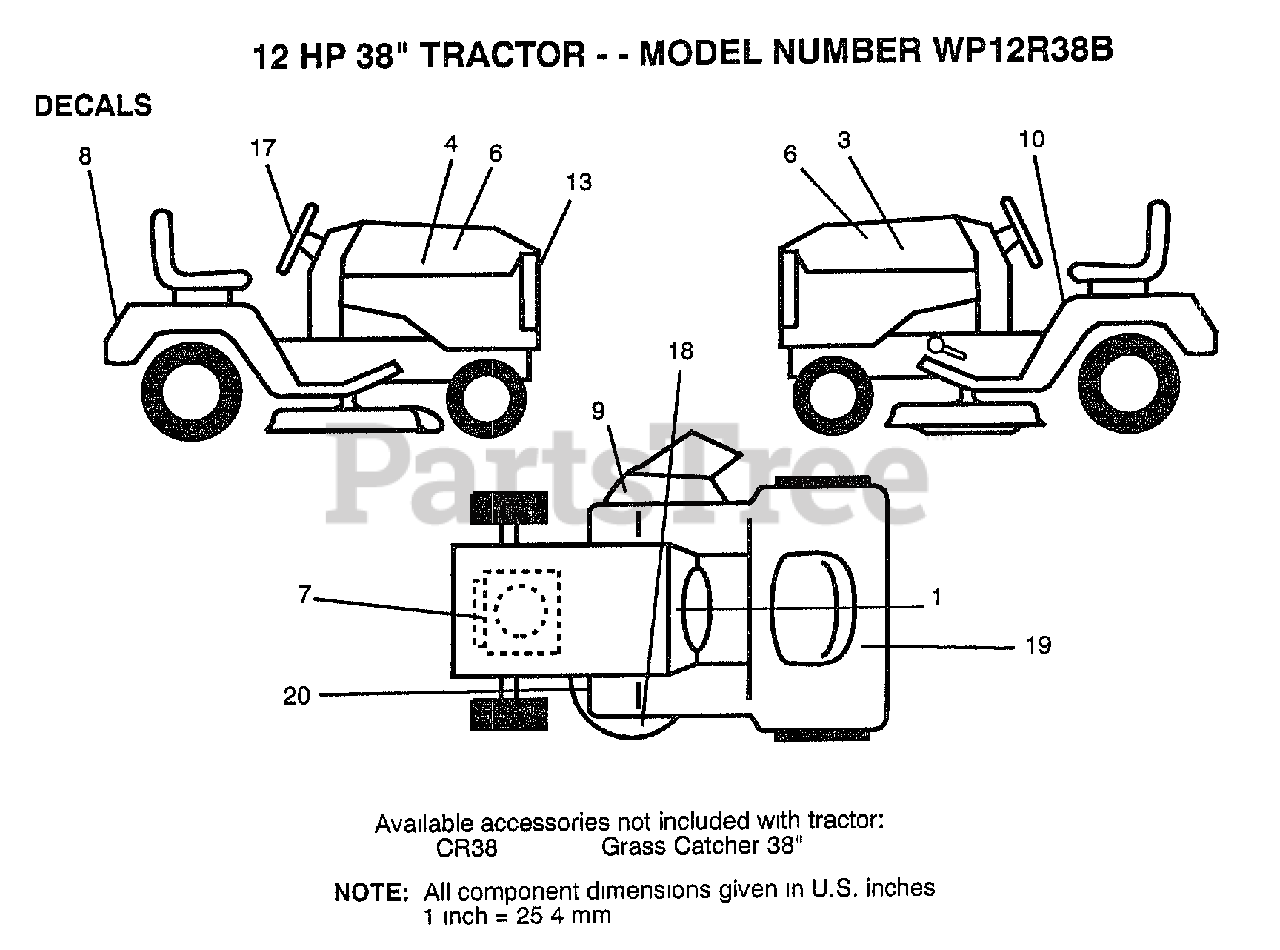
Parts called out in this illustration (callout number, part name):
1	DECAL.INST.OPER.
5	IND HGT DECK DECA
6	DECAL.HOOD.LOGO.
7	DECAL.ENG.271967
8	DECAL, FENDER LOGO
9	"DECAL, WARNING"
10	DECAL CAUTION
13	"DECAL,LIGHT BOX"
17	DECAL, WHEEL CAP
19	DECAL
20	DECAL
